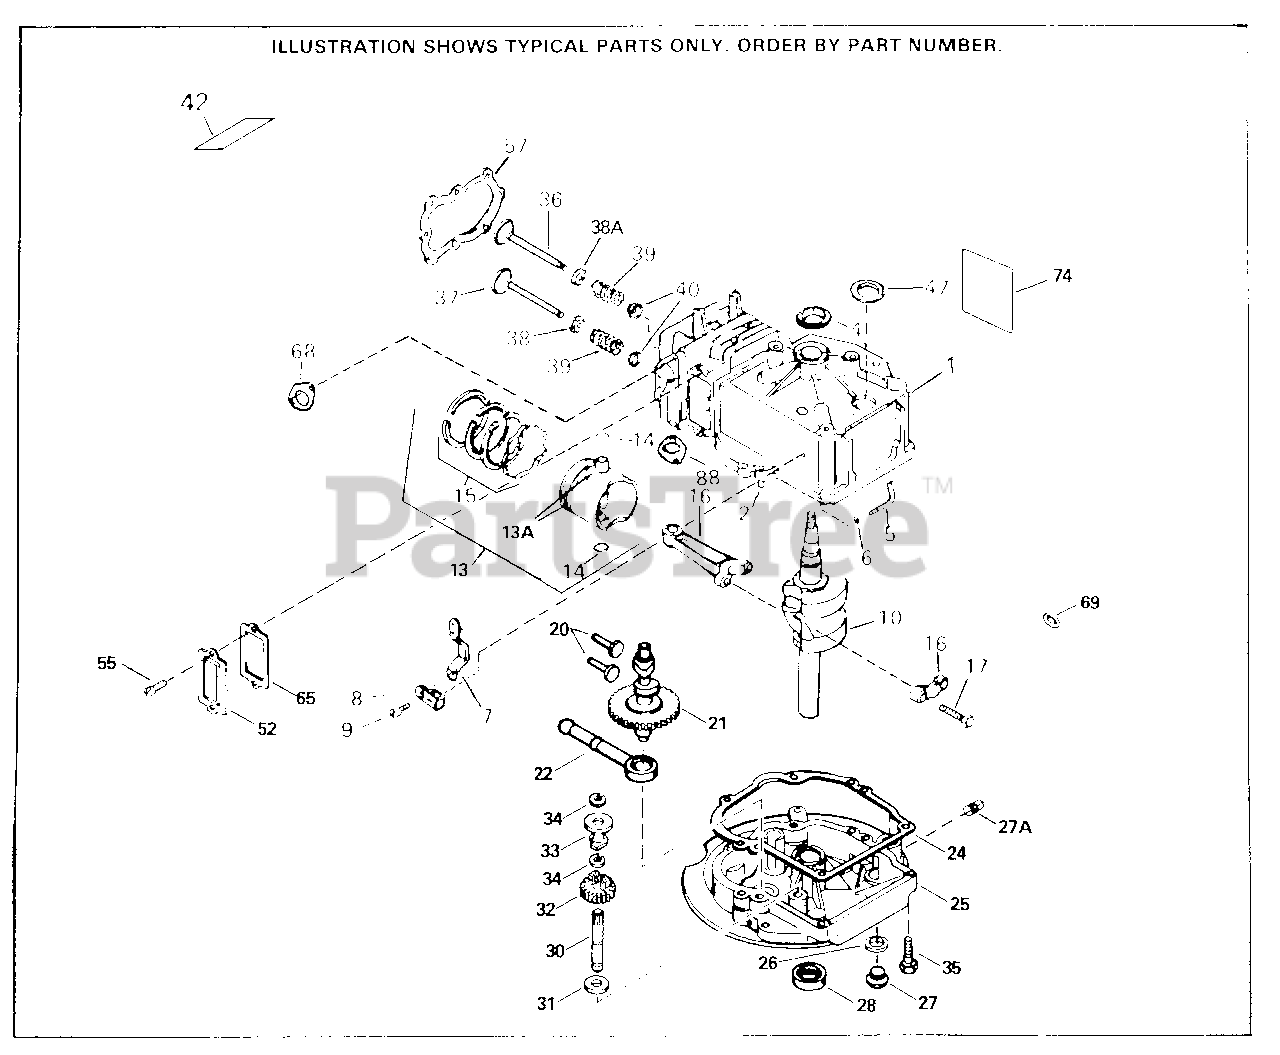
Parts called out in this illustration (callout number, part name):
1	"Cylinder (Incl. 2 & 4) (2-5/8" Bore)
2	Dowel Pin
4	Seal, Oil
5	Rod, Governor (Incl. 6)
6	Flat Washer
7	Lever, Governor
8	Clamp, Governor lever
9	Screw, 8-32 x 5/16"
10	Crankshaft
13	Piston, Pin & Ring Set (.010" OS)
13	Piston, Pin & Ring Set (.020" OS) (In cl. 41, 42 & 43)
13	Piston, Pin & Ring Set (Std.) 2-5/8"B ore
13A	Piston & Pin Assembly (Std.) (Incl. 4 3)-5/8")
13A	Piston & Pin Assembly (.010" OS) (Inc l. 43)OS)
13A	Piston & Pin Assembly (.020" OS) (Inc l. 43)OS)
15	Ring Set (Std.) (2-5/8" Bore)
15	Ring Set (.010" OS)
15	Ring Set (.020" OS)
16	Rod Assy., Connecting (Incl. 17)
17	Bolt, Connecting rod
20	Valve Lifter
21	Camshaft (MCR)
22	Oil Pump Ass'y.
24	Mounting Flange Gasket
25	Flange Assy., Mounting Incl. 27, 28& 30
26	Drain Plug Gasket ed)
27	Plug, Oil drain
27A	Oil Drain Plug
28	Oil Seal
30	Shaft, Mechanical governor
31	Washer, Flat
32	Gear Assy., Governor (Incl. 31)
33	Spool, Governor
34	Retaining Ring
35	Screw, 1/4-20 x 1-1/4"
36	Intake Valve (Std.) (Incl. 151)
36	Exhaust Valve (1/32" OS) (Incl. 151)
37	Exhaust Valve (Std.) (Incl. 151)
37	Exhaust Valve (1/32" OS) (Incl. 151)
38	Cap, Upper valve spring
38A	Seal Assy., Intake valve
39	Spring, Valve
40	Cap, Lower valve spring
42	Decal, Model & Serial number
47	Gasket, Breather
57	Gasket, Cylinder head
65	Valve Cover Gasket
68	Gasket, Intake pipe
69	Washer, S.E. brake
88	Exhaust Gasket
